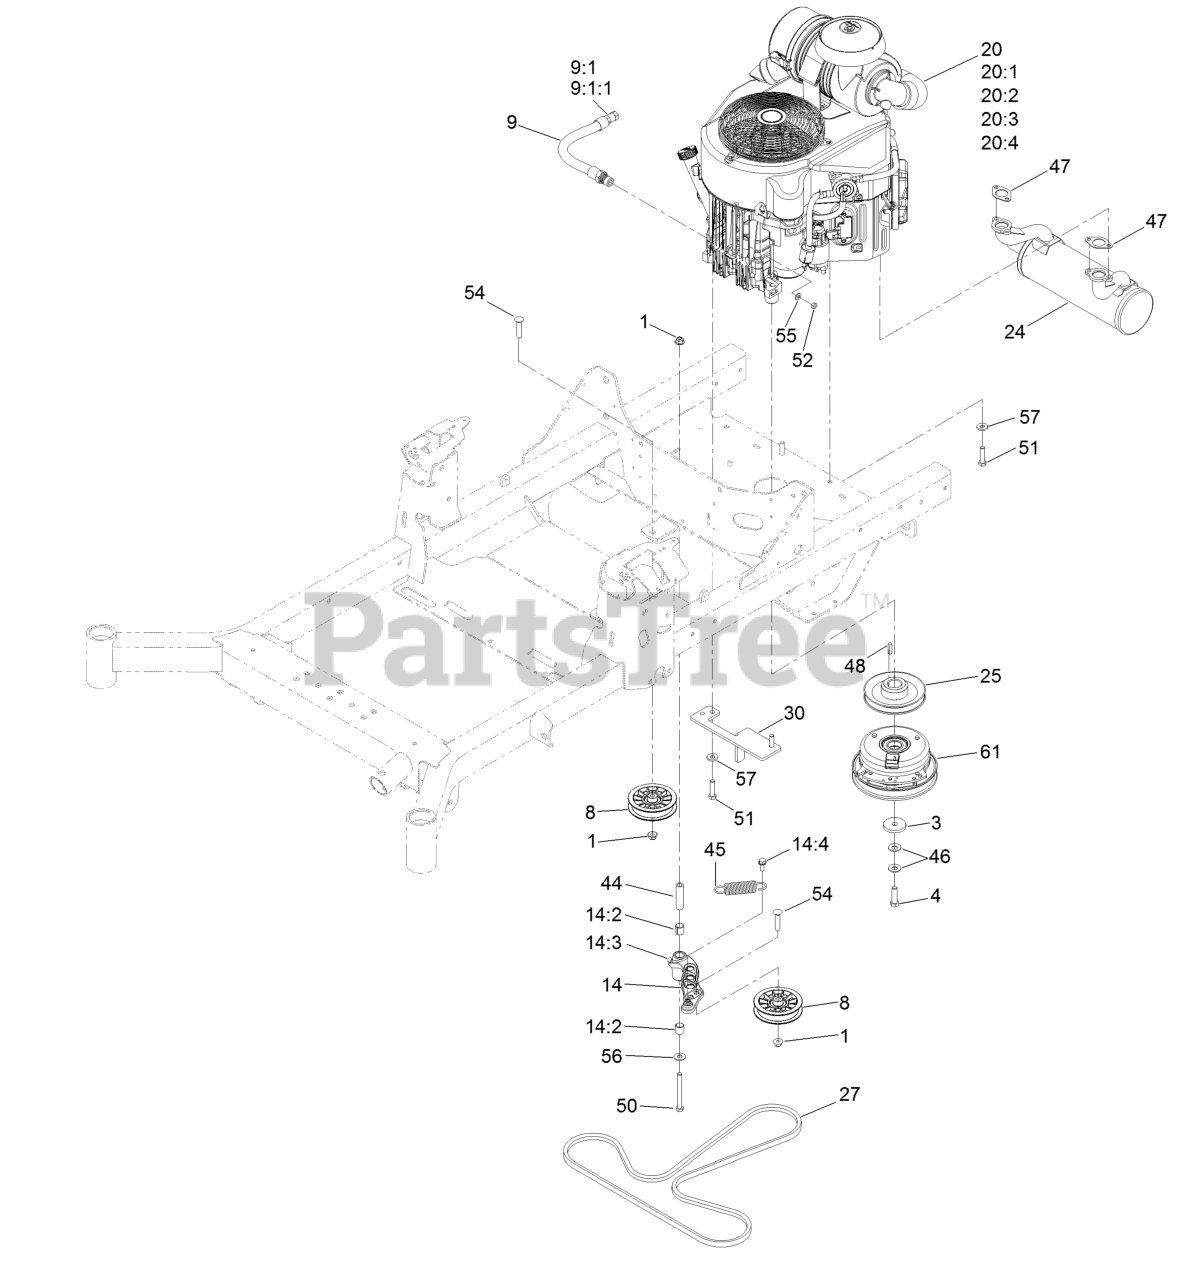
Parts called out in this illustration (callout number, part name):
1	Nut-HF, NI
3	Washer-Clutch
4	Screw-HH
8	Pulley-Flat
9	Engine Oil Drain Hose ASM
9:1	Plug-HH
9:1:1	O-Ring
14	Idler Arm ASM
14:2	Sleeve-Bearing
14:3	Fitting-Grease, 90 DEG
14:4	Screw-HWHTF
20:1	Kawasaki 49065-7007 Engine Oil Filter
20:2	Kawasaki 49019-7005 Fuel Filter
20:3	Kawasaki 11013-7045 Safety Filter
20:4	Kawasaki 11013-7044 Engine Air Filter
24	Muffler
25	Sheave (W/Hub)
27	Belt-V
30	Anchor-Clutch
44	Bushing-Pivot, Idler
45	Spring-Extension
46	Washer-Spring
47	Gasket-Exhaust
50	Screw-HH
51	Screw-HH
52	Nut-Hex
54	Screw-CARR
55	Washer-Flat
56	Washer-Flat
57	Washer-Belleville
